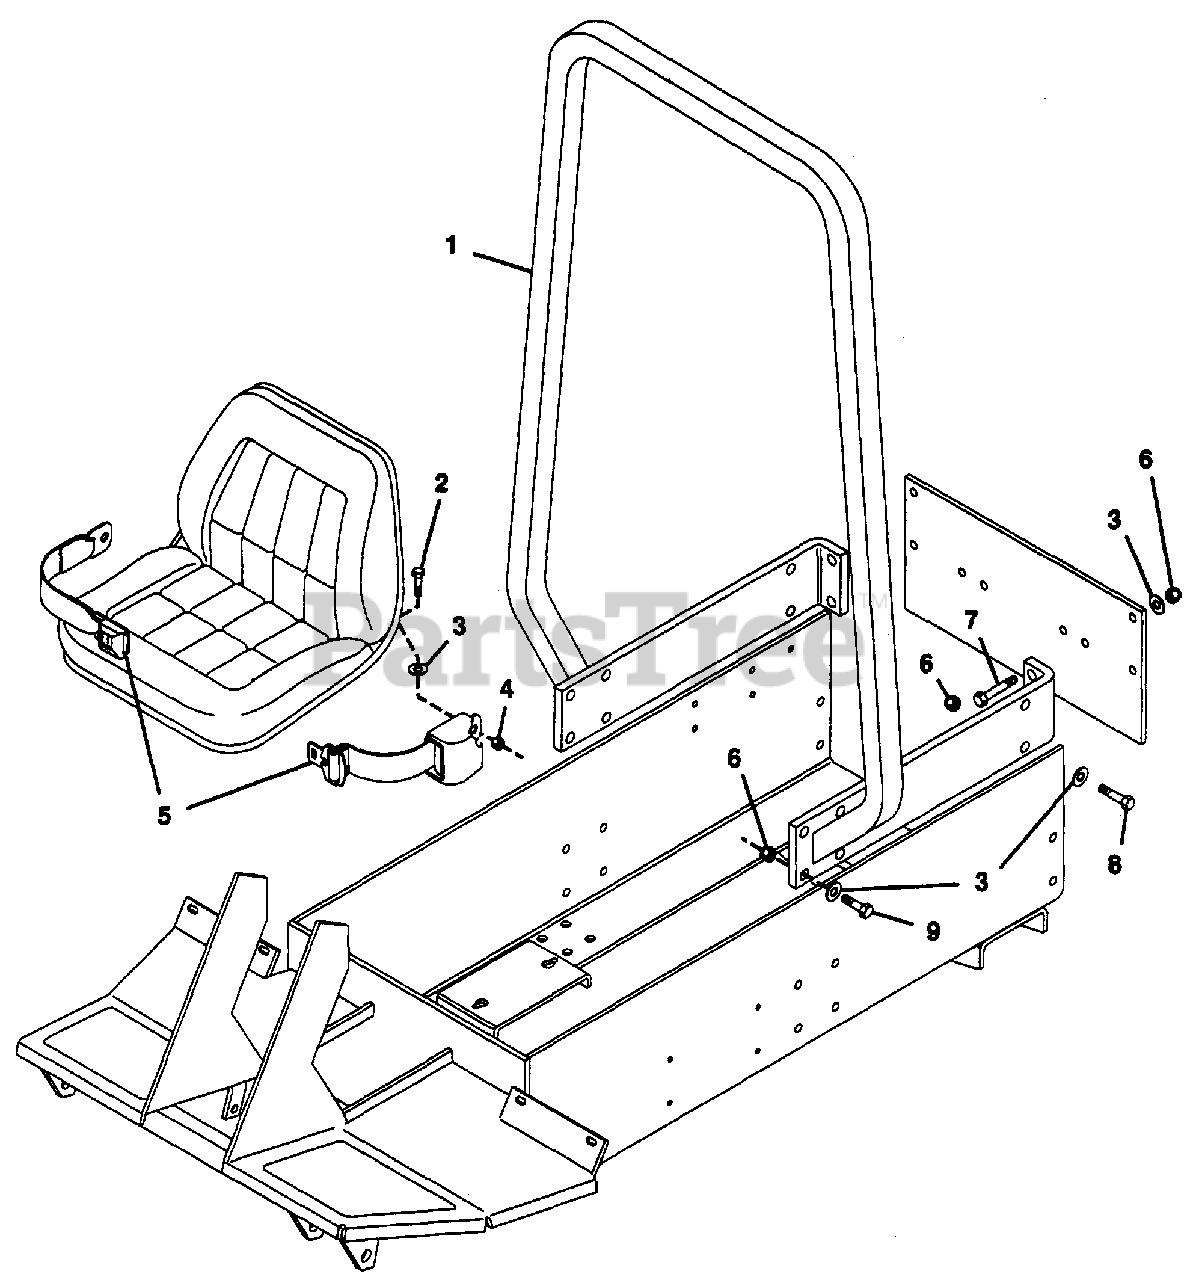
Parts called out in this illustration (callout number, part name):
1	Weldment, Rollover Bar
2	Bolt, Hex 7/16-14x1.00
3	Washer, Flat .531x1.062x.095
4	Nut, Lock 7/16-14
5	Assembly, Seat Belt
6	Nut, Lock 1/2-13
7	Bolt, Hex 1/2-13x2.75
8	Bolt, Hex 1/2-13x1.50
9	Bolt, Hex 1/2-13x1.25
